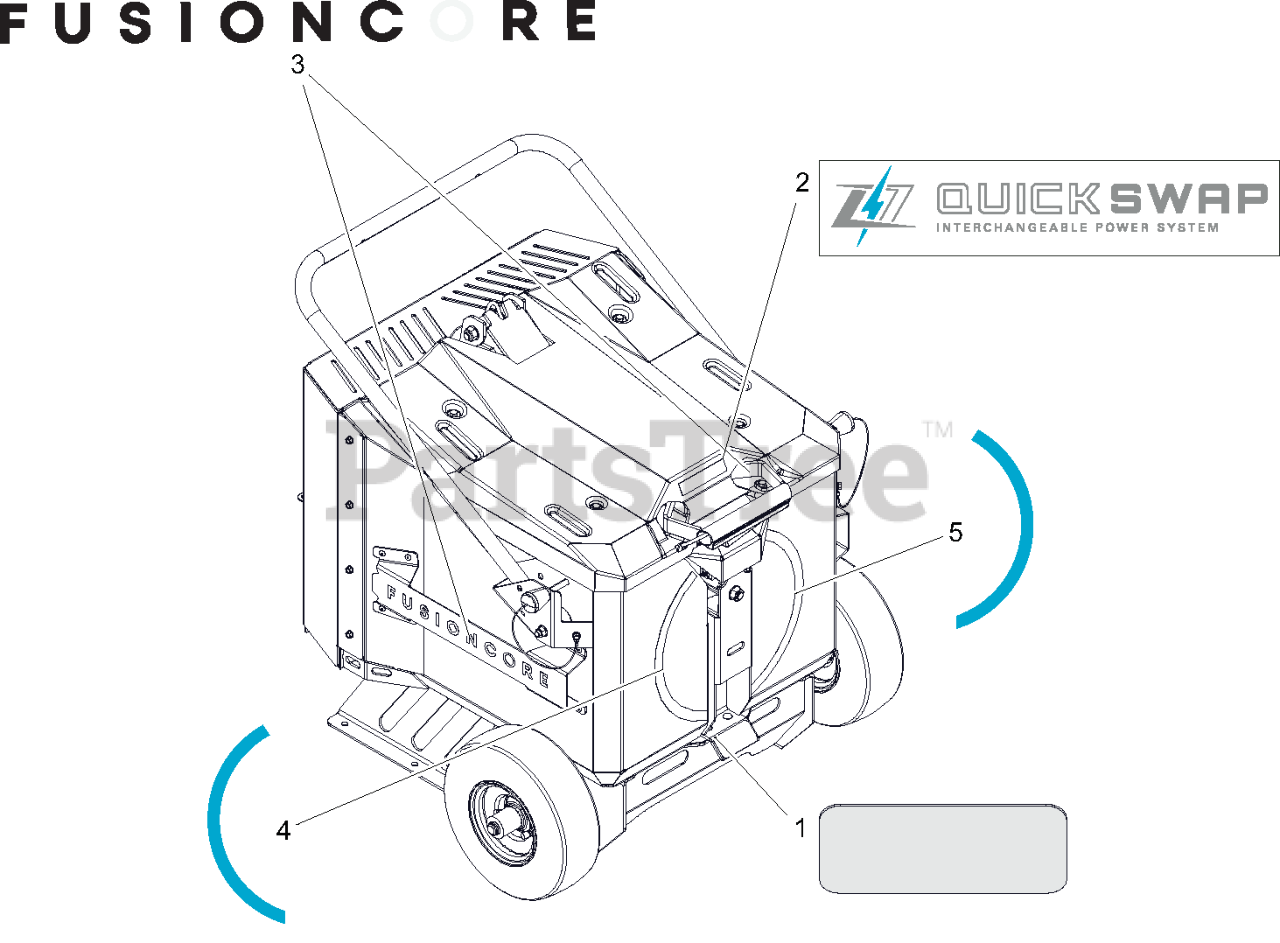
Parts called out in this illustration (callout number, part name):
1	GRIP, PEDAL 1.50 X 3.00
2	DECAL, QUICK SWAP -HATCH
3	DECAL, FUSIONCORE
4	DECAL, FUSION -LH
5	DECAL, FUSION - RH
